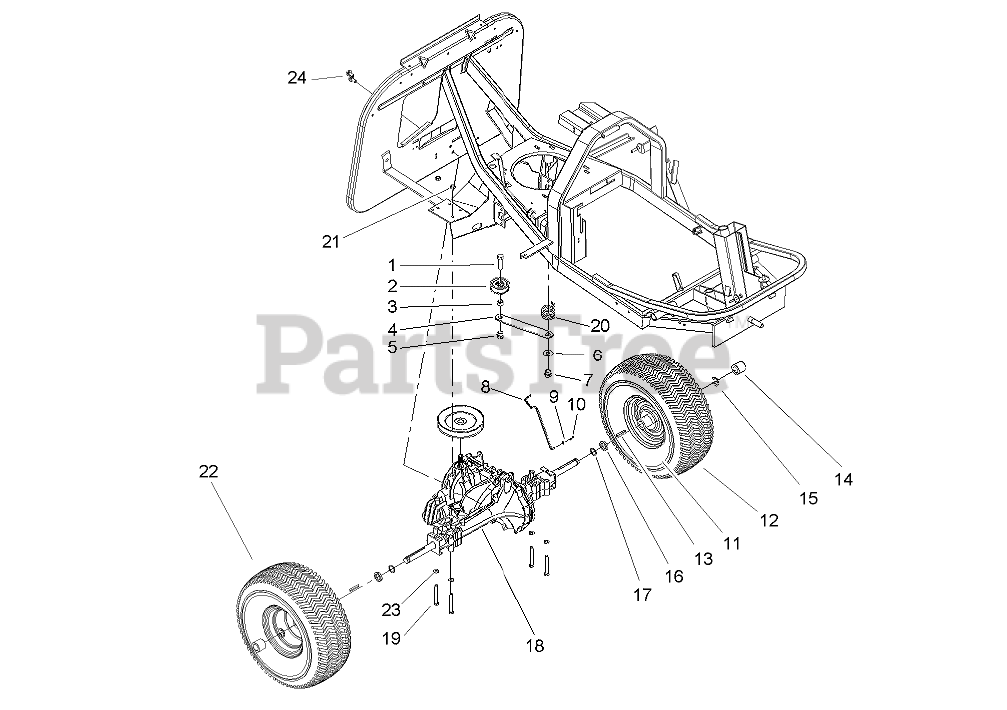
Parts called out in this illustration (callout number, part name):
1	Screw-HH
2	PULLEY ASM
3	Spacer-Idler
4	Bracket
5	NUT-LOCK
6	Washer-Flat
7	NUT-LOCK, NI
9	Washer-Flat
10	Pin-Hair
11	WHEEL-LH
13	Key-Square
14	Spacer
15	RING-RETAINING, EXT
16	Spacer
17	Washer-Flat
18	TRANSAXLE-HYDRO
19	Screw-HH
20	Spring-Extension
21	NUT-LOCK
22	WHEEL-RH
23	WASHER-PLAIN
24	SCREW-HHF TAP
